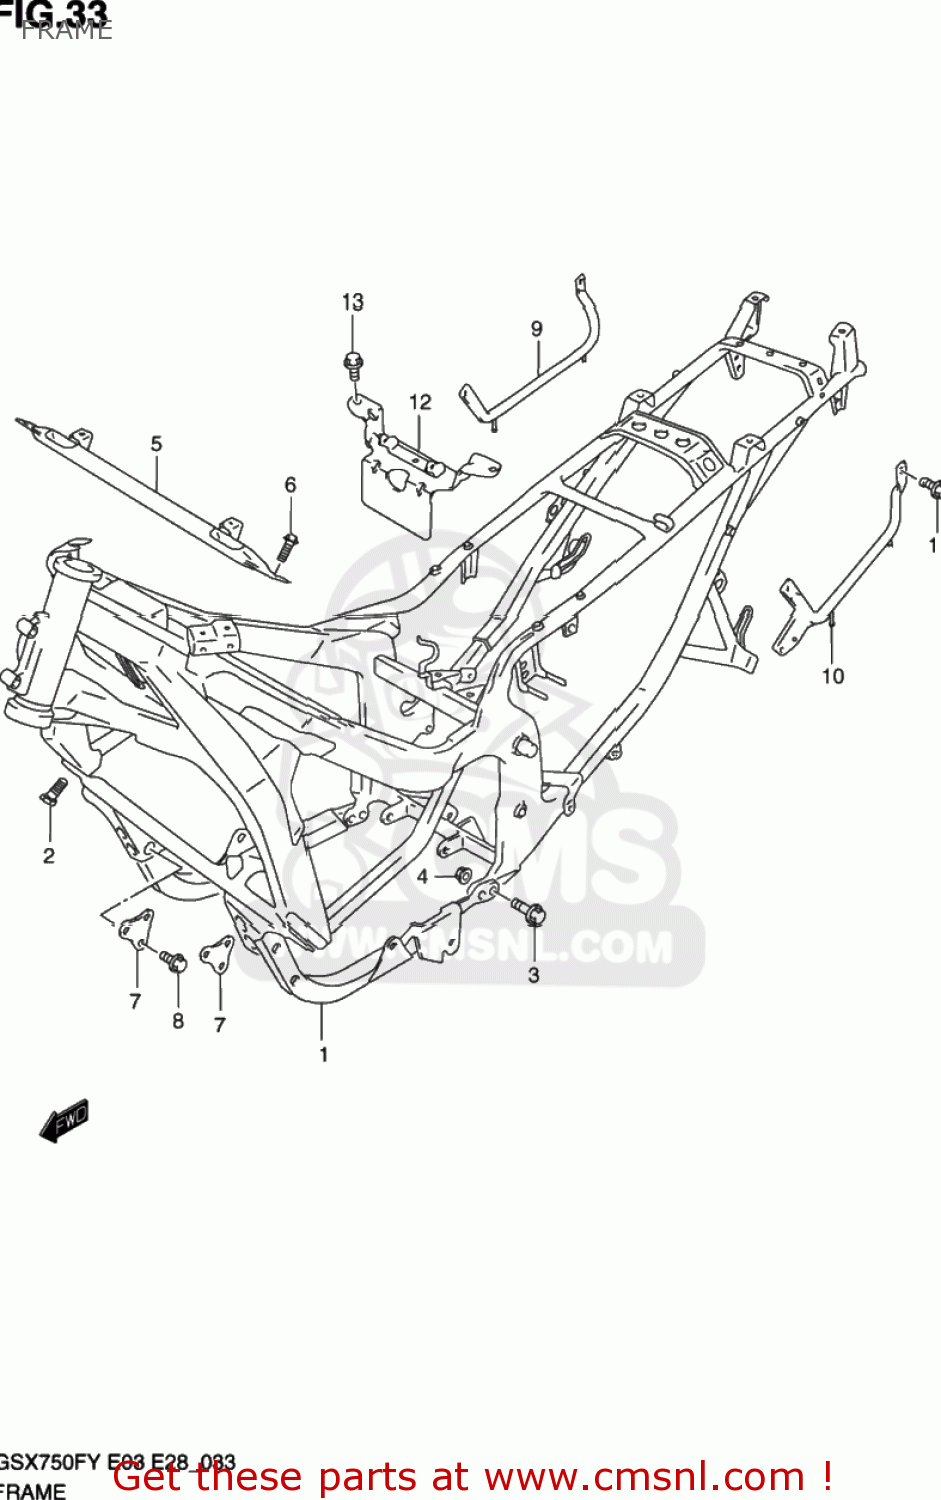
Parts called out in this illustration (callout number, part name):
1	FRAME(BLACK)
2	BOLT
3	BOLT
4	NUT
5	TUBE,FRAME BRIDGE NO.2
6	BOLT(8X20)
7	PLATE,ENG MTG NO.1
8	BOLT, UPPER
9	GRIP,RR,R
10	GRIP,RR,L
11	BOLT
12	PLATE,ELECTRIC PARTS HOLDER
13	BOLT
